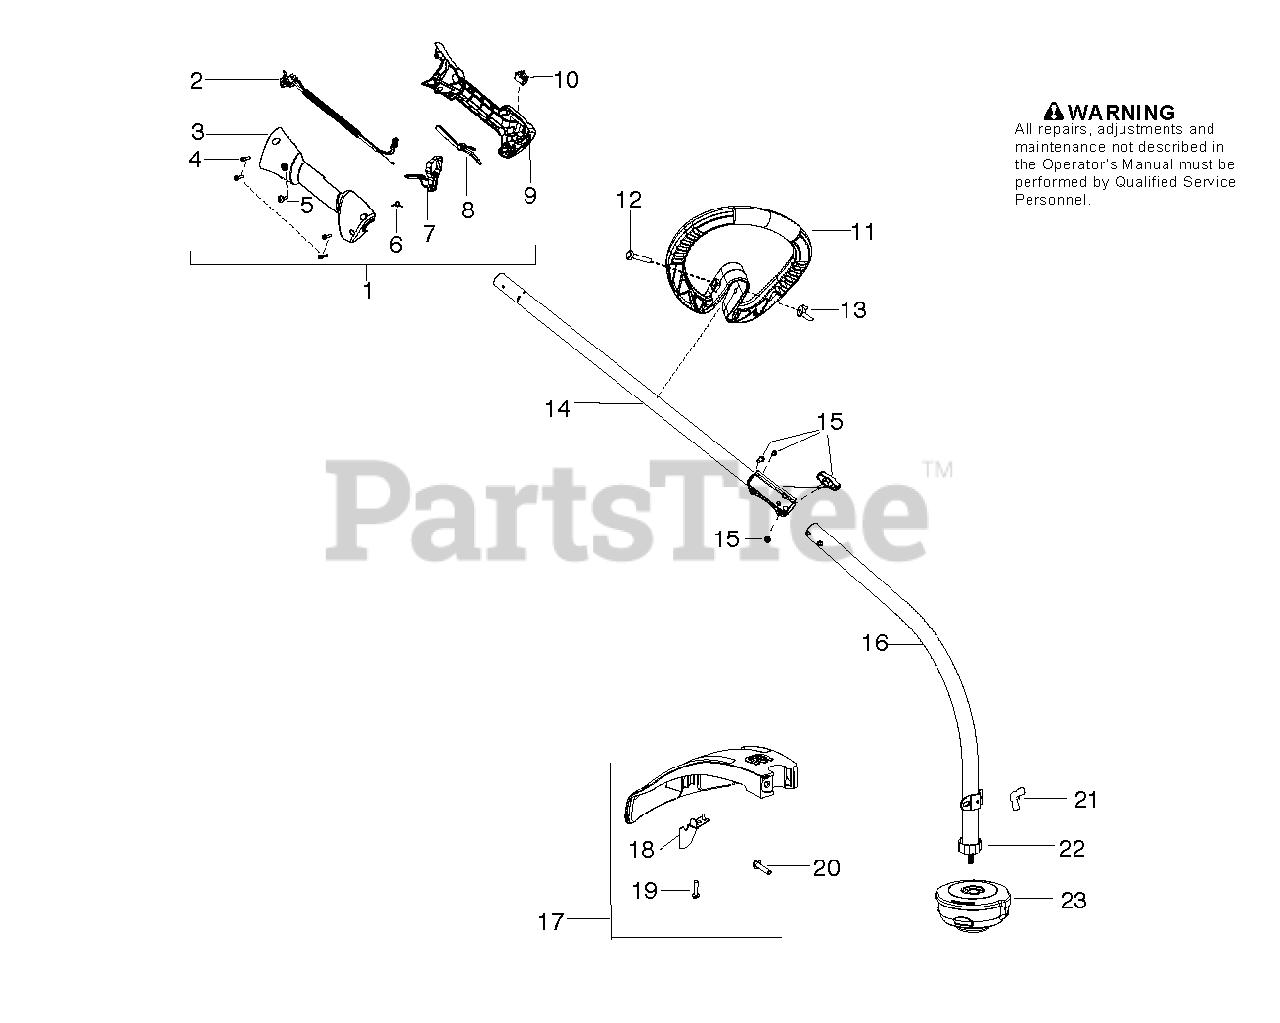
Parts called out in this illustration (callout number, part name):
2	ASSY CABLE/WIRE HARNESS
3	HANDLE HALF RIGHT
4	SCREW M4 X 1.75 PT 16MM
5	SCREW M4 X 1.75 PT 16MM
8	LOCKOUT TRIGGER
9	HANDLE HALF LEFT
10	STOP SWITCH
11	HANDLE ASSIST 1"
12	BOLT, TYPE 2
13	WINGNUT, TYPE 2
14	Drive Shaft Kit, Upper
15	ASSY COUPLER BLACK
16	KIT DRIVE SHAFT LOWER CD
17	Shield Kit
18	LINE LIMITER
20	BOLT, TYPE 2
21	WINGNUT, TYPE 2
22	DUST CUP
23	Trimmer Head Assembly, Tng P25 Pp28 Clockwise
